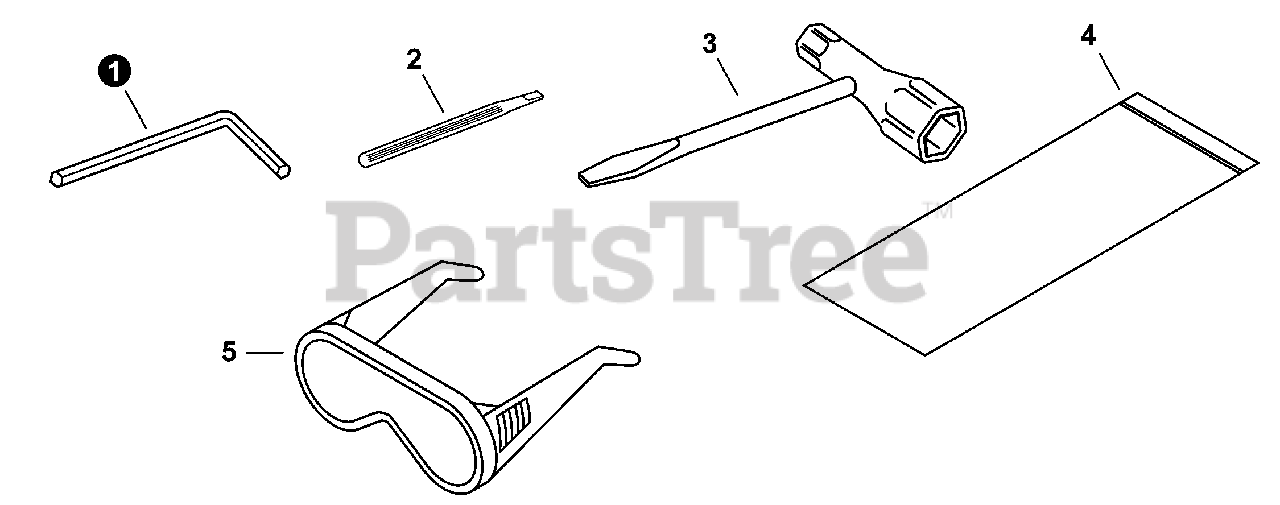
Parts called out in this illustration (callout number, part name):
1	WRENCH, ALLEN 4 MM
2	SCREWDRIVER, PLASTIC
3	T-WRENCH 13×19 L= 180
4	BAG, TOOL
5	GLASSES, SAFETY
